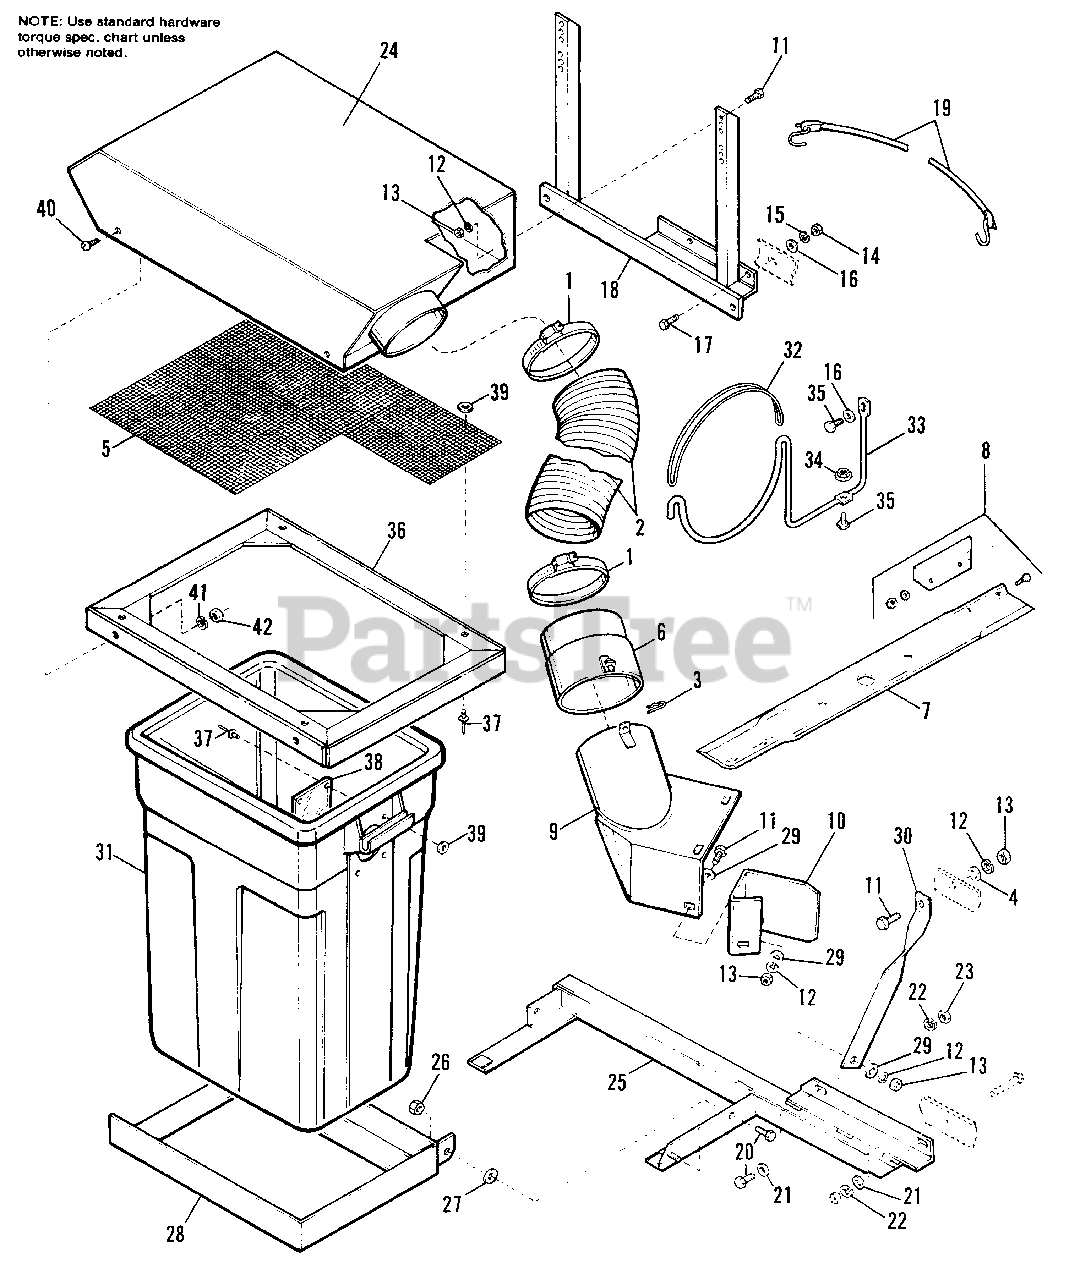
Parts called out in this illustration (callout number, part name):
1	CLAMP, Hose
2	HOSE, Blower, 41"
3	HAIRPIN, Cotter
4	WASHER, Plain
6	TUBE ASSY., Adapter
7	BLADE, Mower
8	AIR LIFT KIT, Mower Blade
9	BOOT ASSY., Discharge
10	ADAPTER BOOT
11	CAPSCREW, Hex, 5/16-18 x 3/4
12	LOCKWASHER, Spring, 5/16
13	NUT, Hex, 5/16-18
14	NUT, Hex, 1/4-20
15	LOCKWASHER, 1/4
16	WASHER, Plain
17	CAPSCREW, Hex, 1/4-20 x 3/4
18	BUMPER ASSY.
20	CAPSCREW, Hex, 3/8-16 x 3/4
21	WASHER, Plain
22	LOCKWASHER, Spring, 3/8
23	NUT, Hex, 3/8- 16
24	HOOD ASSY.
25	FRAME ASSY., Mounting
26	NUT, Hex, Fiber Lock, 3/8-16
27	WASHER, Plain
28	TRAY ASSY.
29	WASHER, Plain
30	STRAP, Grass Catcher
31	CONTAINER, 30 Gallon
33	ROD, Tube Support
34	NUT, Hex Whiz, 1/4-20
35	CAPSCREW, Hex 1/4-20 x 3/4
36	TOP FRAME ASSY.
37	RIVET, Pop
39	WASHER, Plain, Rivet
40	SCREW, Pan Hd., #10-24 x 1/2
41	LOCKWASHER, Spring, #10
42	NUT, Hex, #10-24
